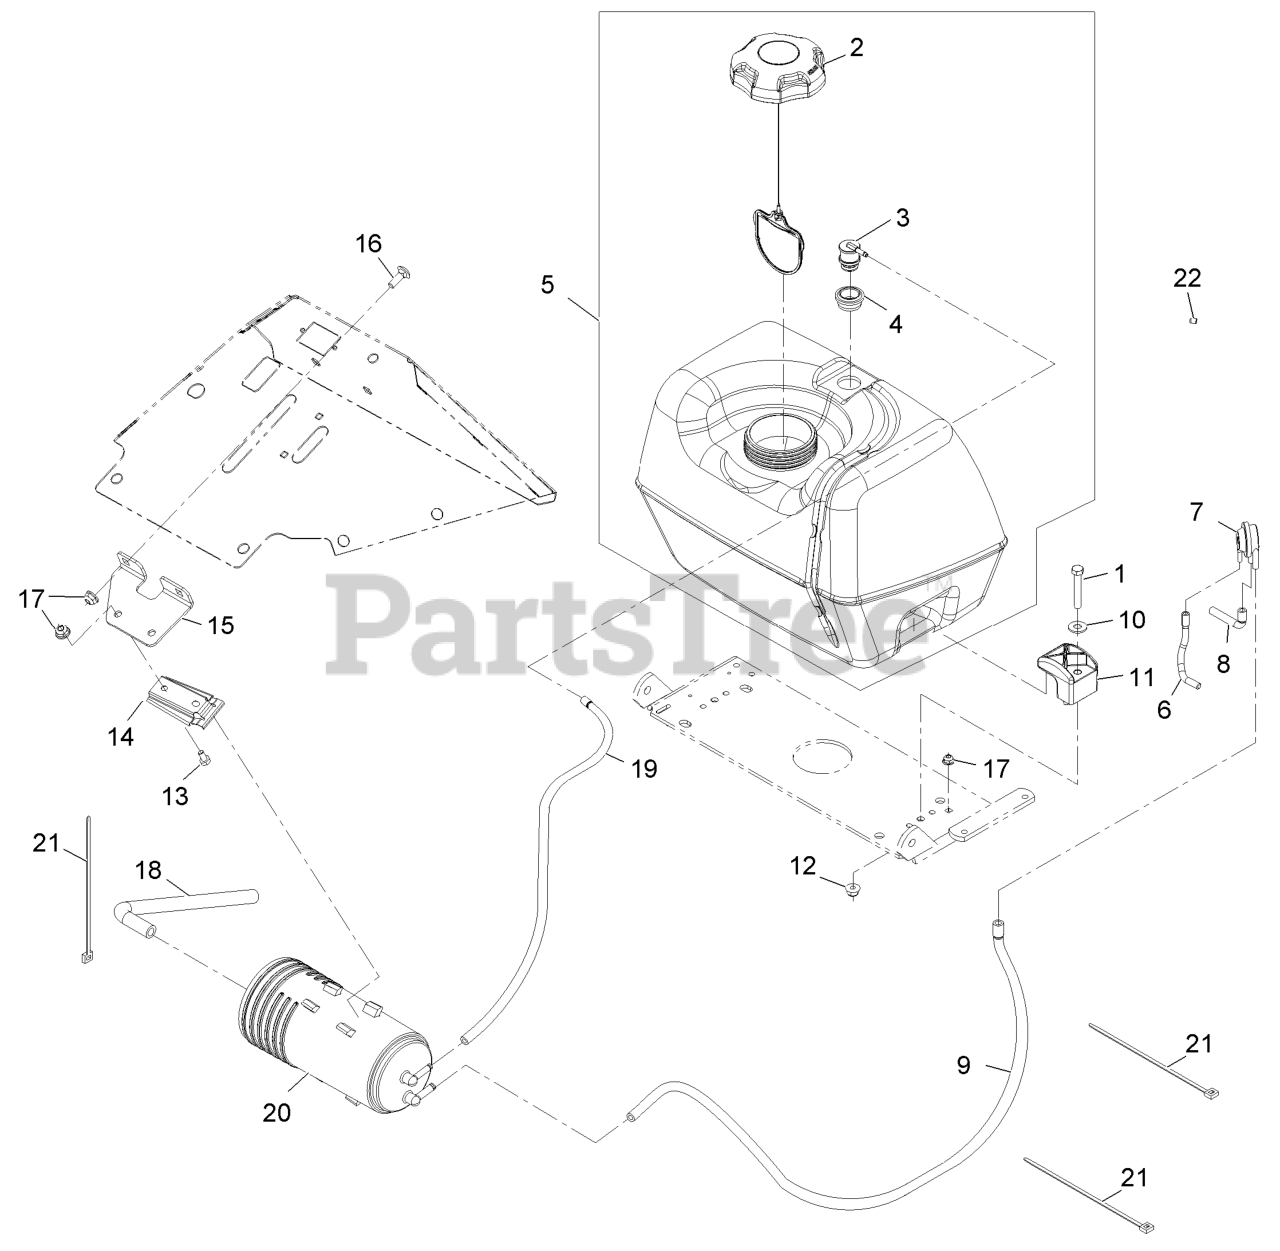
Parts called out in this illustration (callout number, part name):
1	SCREW-HH
6	HOSE-VENT, FORMED
7	VALVE-CONTROL, VACUUM
8	HOSE-VENT, FORMED
9	HOSE-VENT, FORMED
10	WASHER-FLAT
12	NUT-HF, NI
13	SCREW-HH
14	BRACKET-CANISTER, CARBON
15	BRACKET-CANISTER, CARBON
16	BOLT-CARR
18	HOSE-VENT, CANISTER
19	HOSE-VENT
20	CANISTER-CARBON, 800CC
21	TIE-CABLE
22	PLUG-PORT
